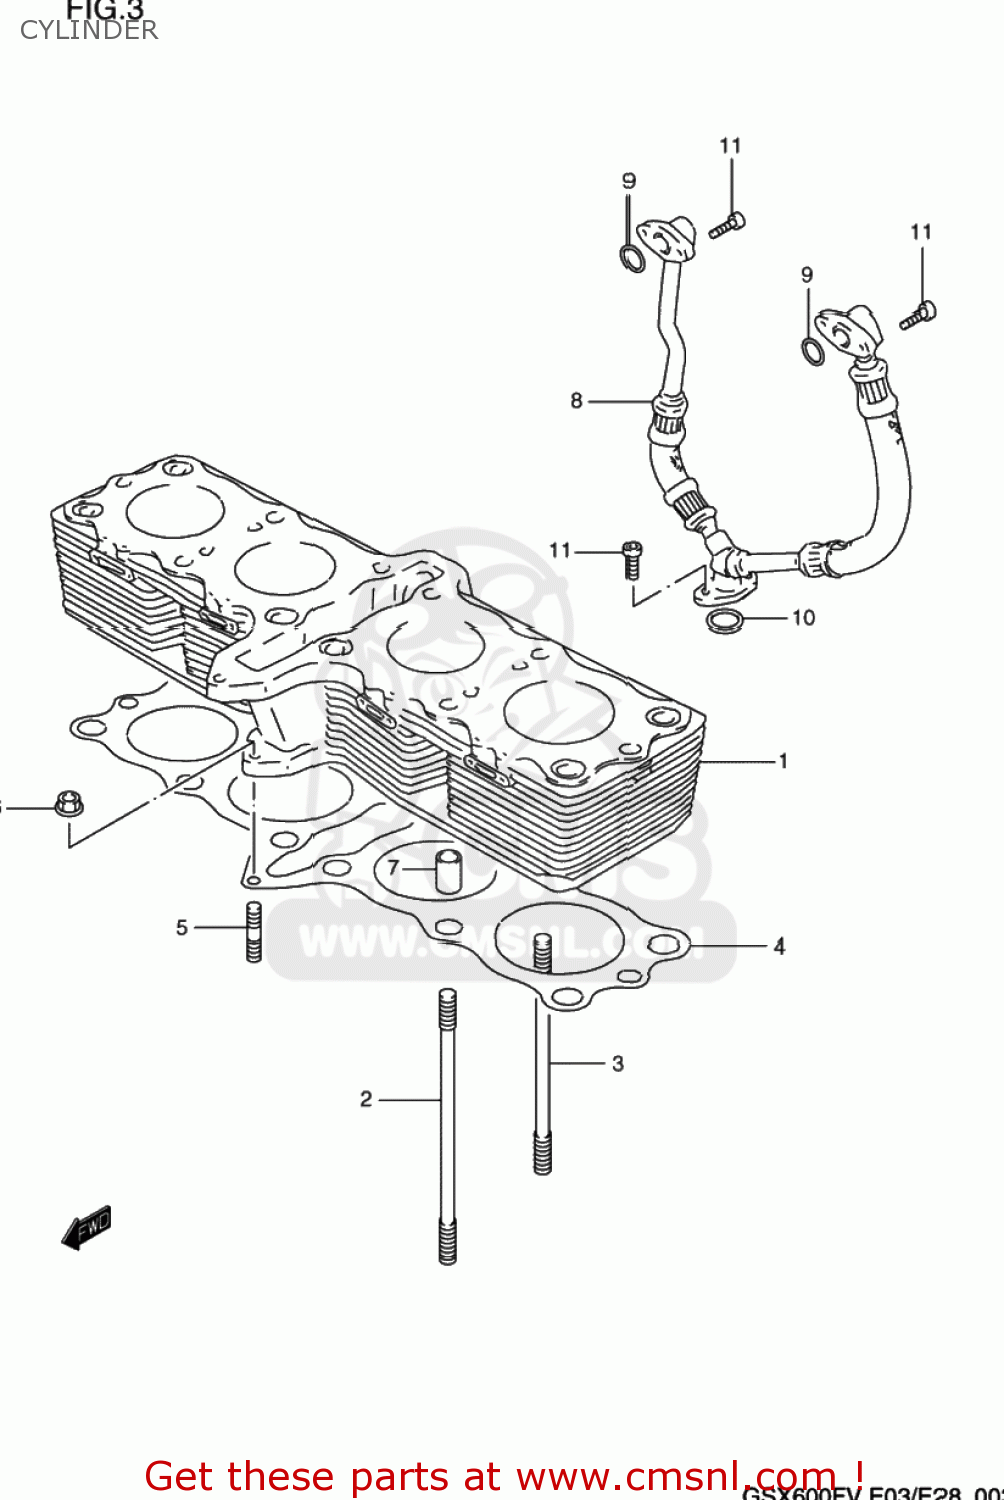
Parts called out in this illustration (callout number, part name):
1	CYLINDER COMP
2	STUD BOLT (L:150)
3	BOLT,STUD
4	GASKET,CYLINDER (NAS)
5	STUD,M6X1X32
6	NUT
7	PIN(13X10.4X20)
8	HOSE,OIL HEAD COOLER
9	O RING(D:2.5,ID:13.8)
10	O RING(D:2.4,ID:15.8)
11	BOLT,OIL FILLE
